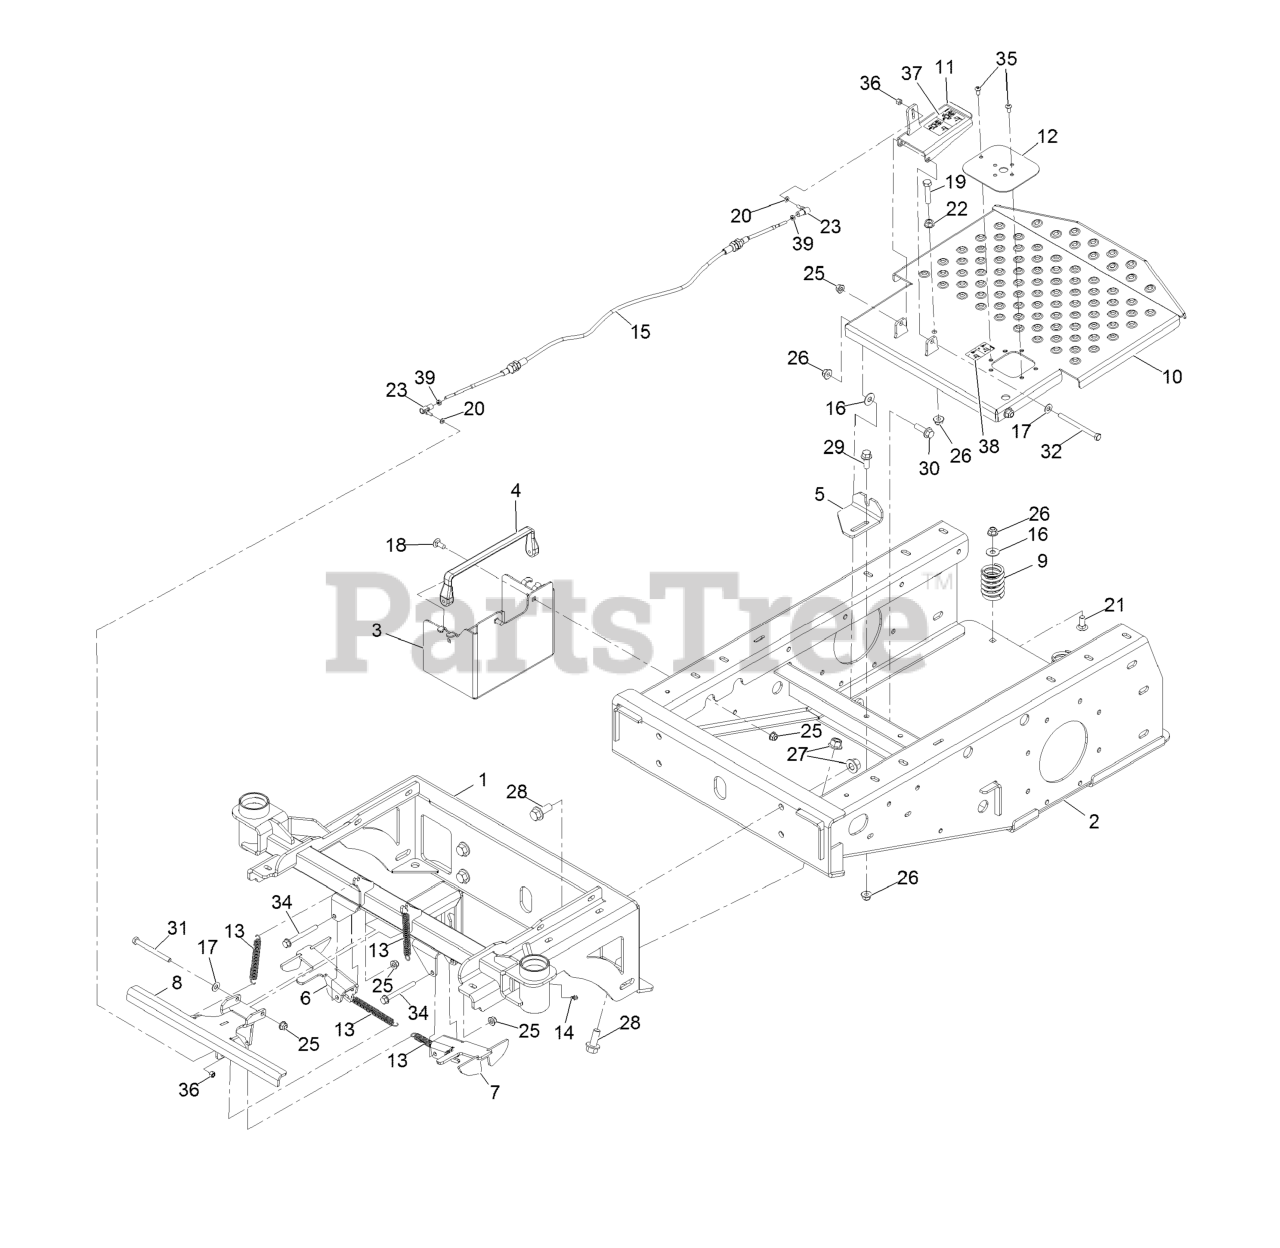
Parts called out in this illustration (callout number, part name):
1	Frame-Front
2	FRAME-REAR
3	BOX-BATTERY
4	BUNGEE (TARP STRAP)
5	Bracket, Lower Cable
6	Wing-Capture, Rt
7	Wing-Capture, Lt
8	Capture-Lcs
9	SPRING-COMPRESSION
10	PLATE-FOOT
11	Pedal-Foot
12	Panel, Foot Switch
13	SPRING-EXTENSION
14	FITTING-GREASE, ZERK
15	CABLE-CASTER, LOCKING
16	WASHER-FLAT
18	SCREW-CARR
19	Screw-HH
20	WASHER-FLAT
21	SCREW-CARR
22	Nut-Hex Flange
23	BALL JOINT-SS
25	Nut-Hex Flange
26	Nut-Hex Flange
27	NUT-HEX FLANGE
28	SCREW-HHF
29	SCREW-HHF
30	SCREW-HHF
31	SCREW-HH
32	Screw-HH
34	SCREW-HHF
35	Screw-HSBH
36	Nut,NYL Lock,#10-32,ST/ST 18-8
37	Decal-Lock, Caster
38	Decal-Spray Foot Button
39	Nut,Hex Jam Mch Scr,10-32,Sst
